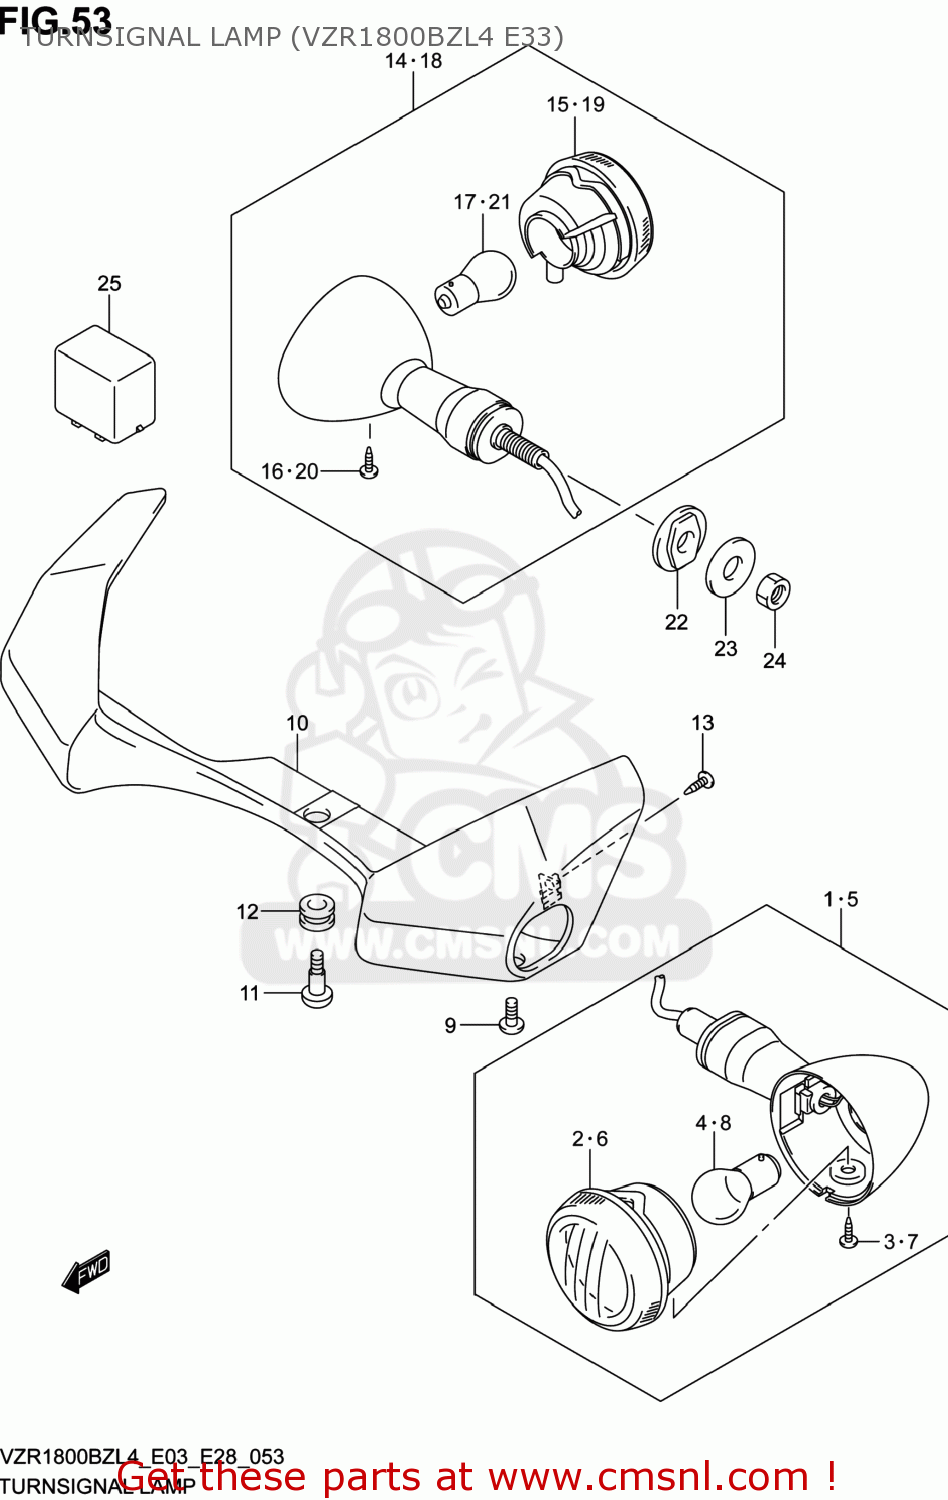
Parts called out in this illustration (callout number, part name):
1	LAMP ASSY,FR TURN SIGNAL,R
2	LENS
3	SCREW(4X10)
4	BULB(12V23/8W)
5	LAMP ASSY,FR TURN SIGNAL,L
6	LENS
7	SCREW(4X10)
8	BULB(12V23/8W)
9	SCREW
10	COVER,FRONT TURNSIGNAL
11	SCREW(6X16)
12	CUSHION
13	SCREW
14	LAMP ASSY,RR TURNSIGNAL,R
15	LENS
16	SCREW(4X10)
17	BULB(12V21W,AMBER)
18	LAMP ASSY,RR TURNSIGNAL,L
19	LENS
20	SCREW(4X10)
21	BULB(12V21W,AMBER)
22	SPACER,RR TURNSIGNAL
23	WASHER(10.5X30X2.3)
24	NUT
25	RELAY ASSY,TURNSIGNAL LAMP
